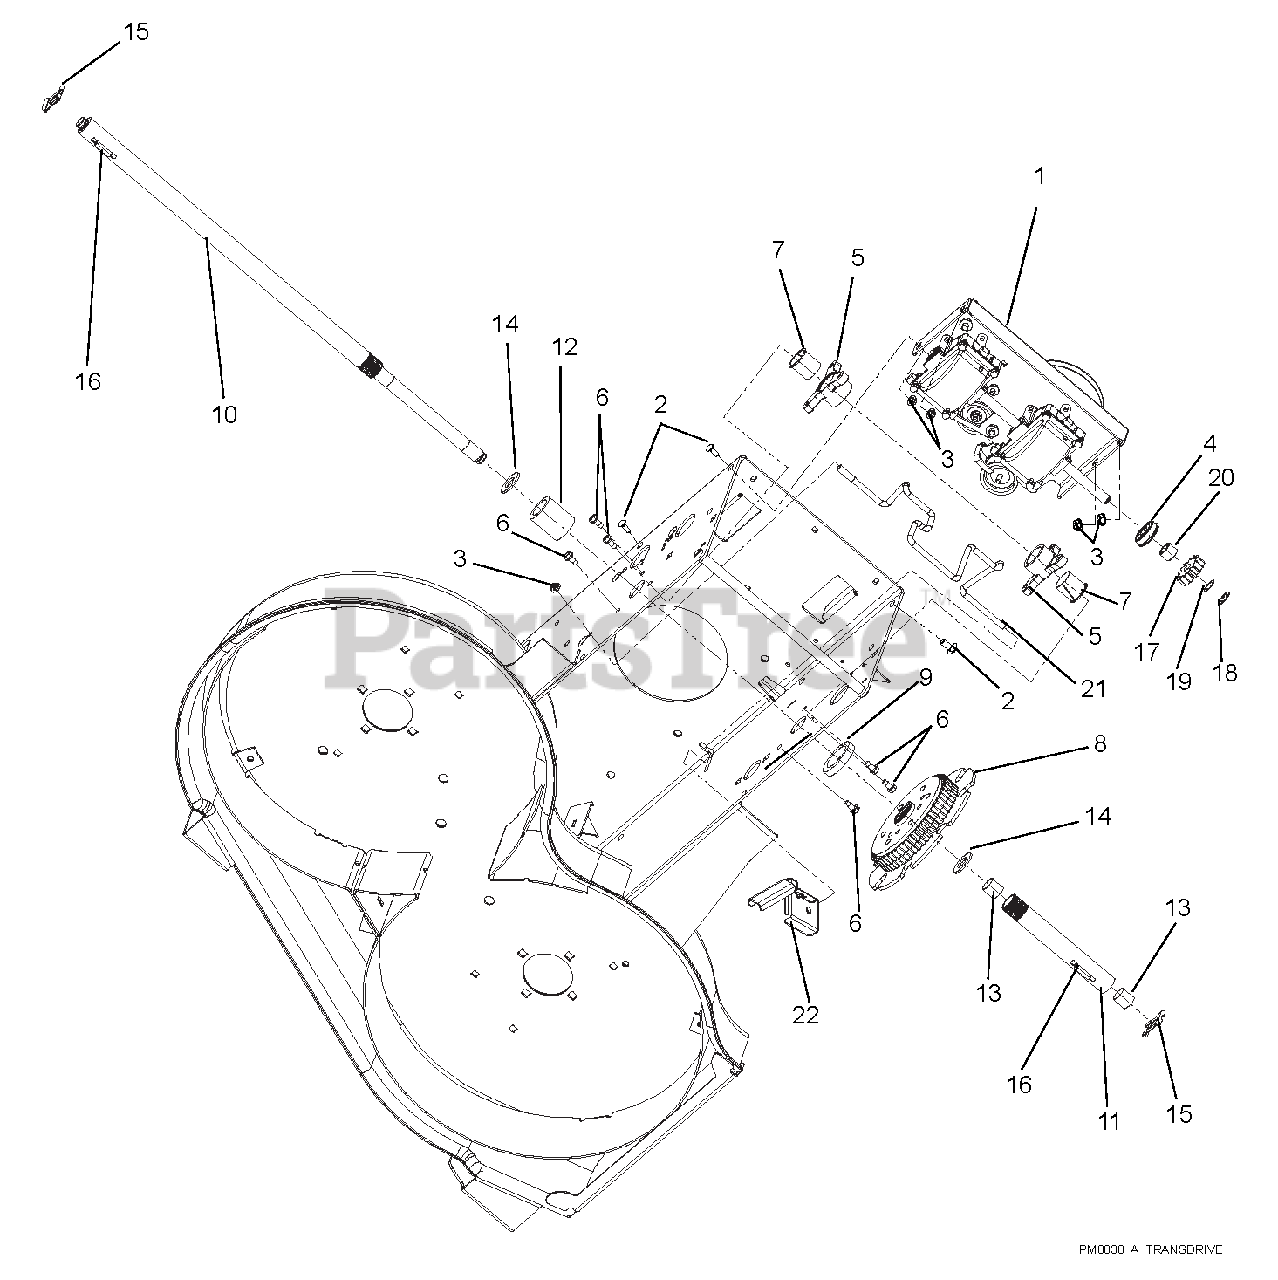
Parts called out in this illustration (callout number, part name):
1	KIT, WAW TRANSMISSION
2	@BLT-RDHDSQNK .31-18X.75 G5YZ
3	@NUT-LK-TOP-FLG .31-18 YWZC
4	BRG-BALL .50X1.38X.438 SEALED
5	BUSHING, RAKE SHAFT 1"
6	@SCR-TAP .25-20X.50 HWH TR YWZ
7	BSHG-FLG SPLIT NYLINER 1.0" HP
8	KIT, WAW DIFFERENTIAL
9	WSHR-FL-NY 1.42X2.03X.35
10	SHAFT-AXLE LONG
11	SHAFT-AXLE, SHORT
12	SPACER, 1.0X1.5X1.57
13	BSHG-SLV .706X.764X.75 BRZ
14	WSHR-FL-STL 1.010X1.505X.062YZ
15	CLIP, SNAP .625 DIA
16	KEY-RECT .25X.188X1.00
17	PINION, TRANSMISSION DRIVE
18	RG-RTNG-EXT .500X.042 (E)
19	WASHER, .500X.750X.020 THRUST
20	RETAINER, BEARING
21	BELT FINGER, WIREFORM
22	GUIDE, VERTICAL BELT
